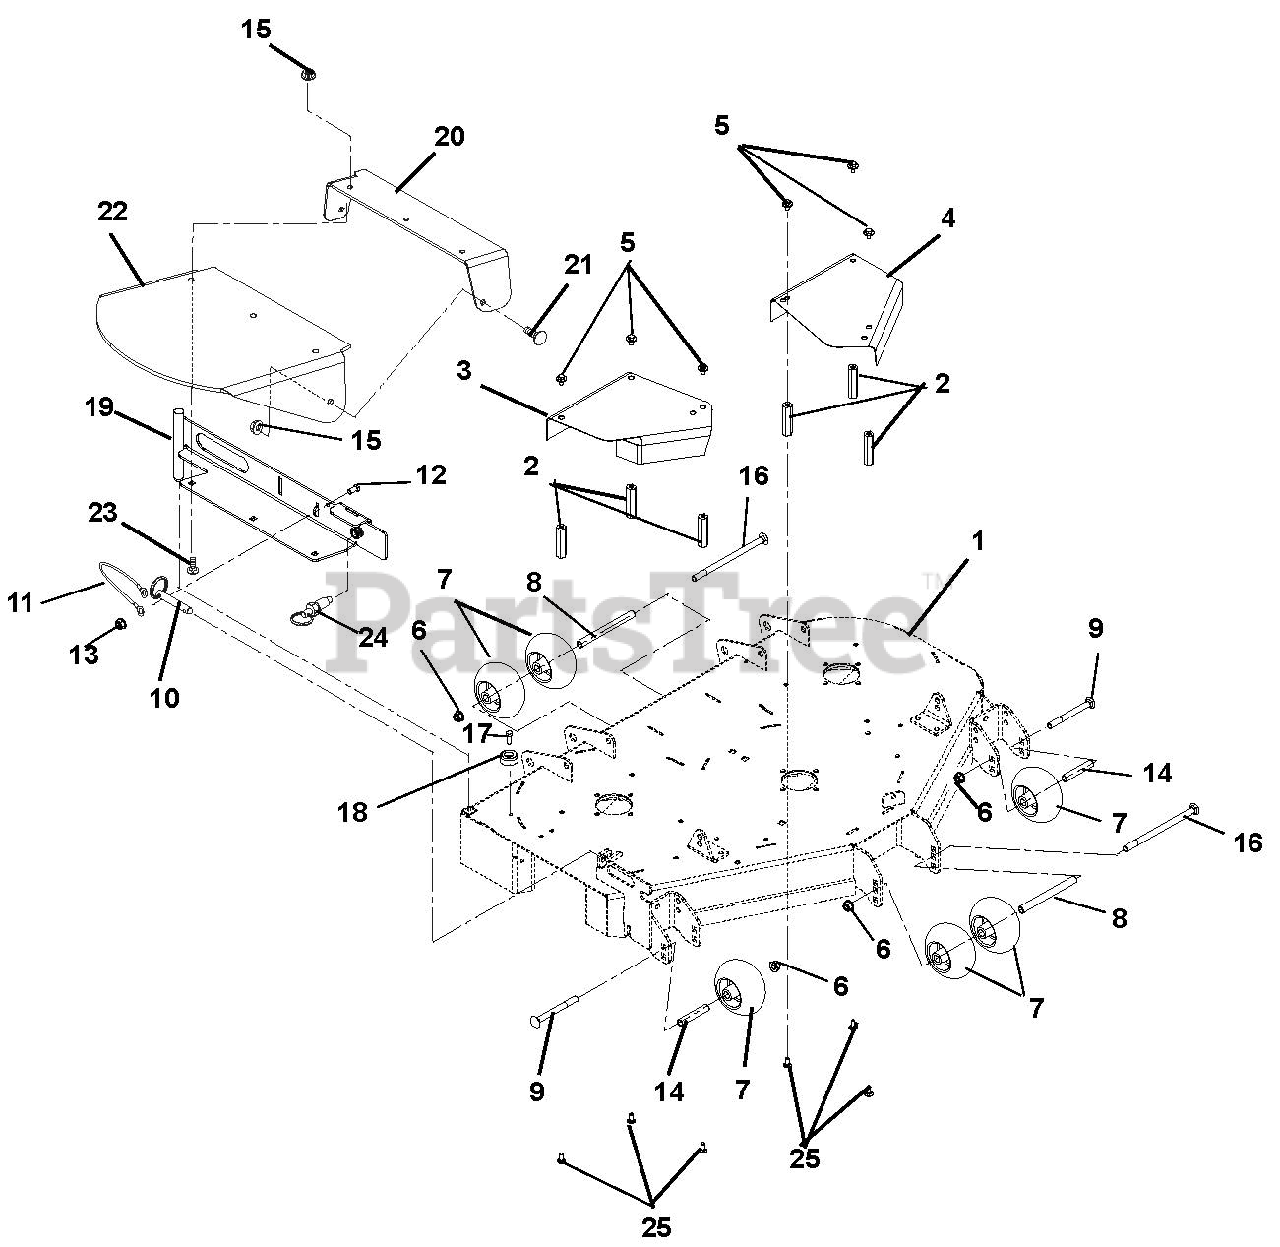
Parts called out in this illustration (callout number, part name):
1	44" Side Discharge Deck Weldment
1	48" Side Discharge Deck Weldment
2	Nut, Coupling .31-18 x 3.00
3	Right Hand Spindle Guard
4	44 in., 48 in., & 52 in. Left Hand Spindle Guard
5	Bolt, SEMS .31-18 x .62
6	Nut .50-13 Nyloc Flange
7	Anti-Scalp Wheel
9	Bolt, Round Head Square Neck .50-13 x 5.00
10	Pin, Spring Ball .375 OD x 1.50
11	Cable, 6.0 Lanyard, Nylon
12	Bolt, Hex .25-20 x .75 Grade 5
13	Nut, Locking Top Flange .25-20
14	Spacer, .510 x .625 x 3.35
15	Nut, .38-16 Nyloc Flange
16	Bolt, Round Head Square Neck .50-13 x 8.50
17	Screw, Tapping .31-18 x .75 Hex Washer Head Thread
18	Bumper, Recessed 1.50 x .63 , .31 Thru Hole
19	44 in. & 48 in. Discharge Chute Mounting Weldment
20	Rubber Discharge Chute Support
21	Bolt, Round Head Square Neck .38-16 x 1.00 Grade 5
22	Chute, Rubber Discharge
23	Bolt, Round Head Square Neck .38-16 x 1.25 Grade 5
24	Pin, Pull
25	Bolt, Round Head Square Neck .31-18 x .75 Loctite
